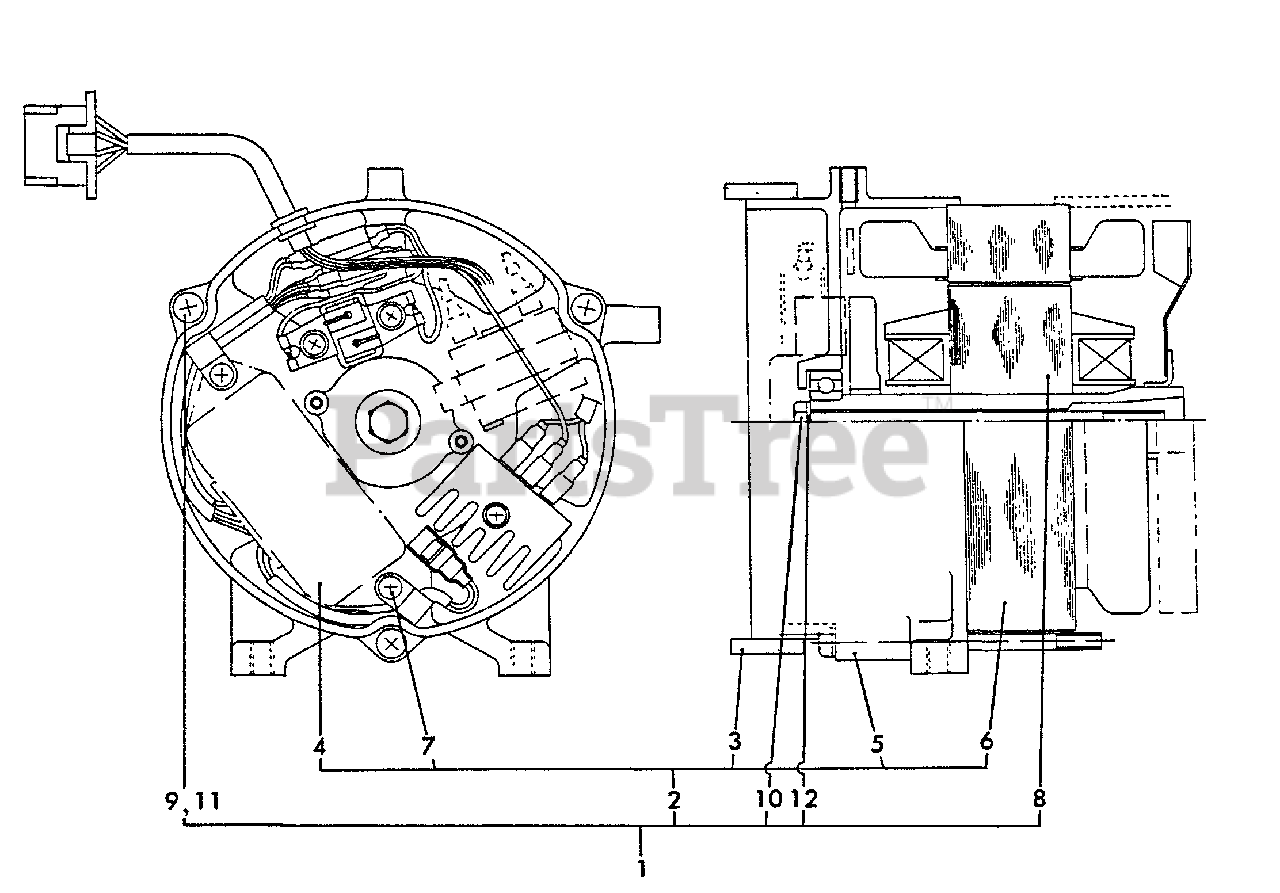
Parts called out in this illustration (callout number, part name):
1	GENERATOR
2	STATOR ASSY
3	URATHANE FOAM
4	CONDENSER
5	COVER - REAR
6	STATOR
7	SCREW - 4×10
8	ROTOR ASSY
9	THROUGH BOLT
10	BOLT
11	LOCKWASHER - 6
12	LOCKWASHER - 8
